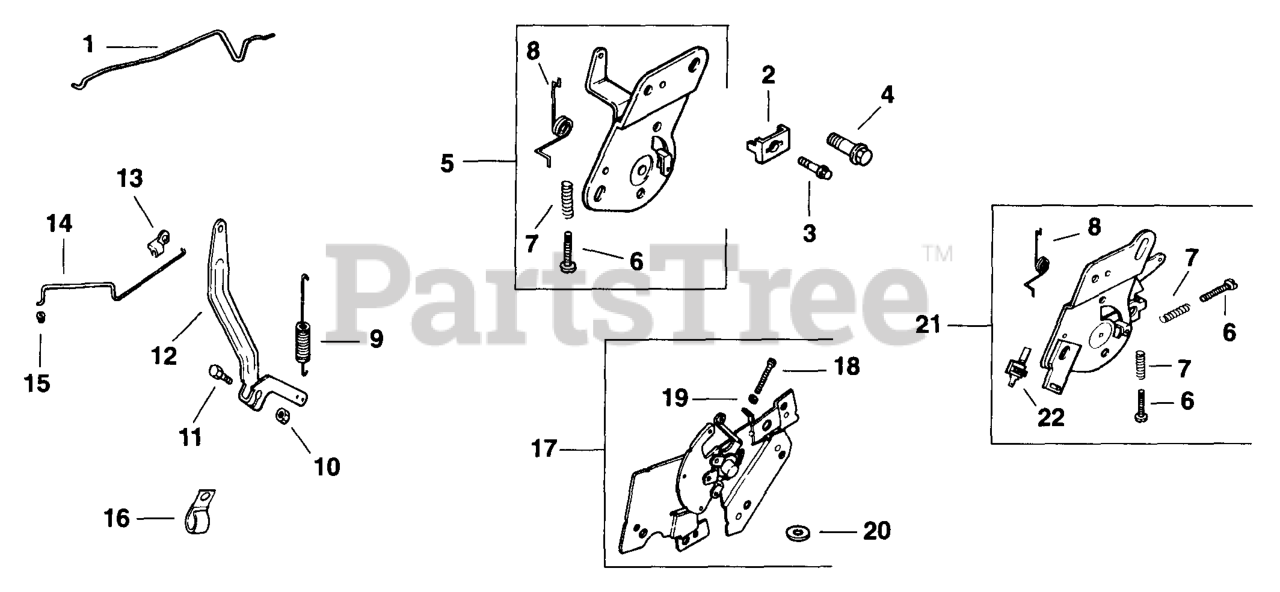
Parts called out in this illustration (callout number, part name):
1	LINKAGE, CHOKE
2	CLAMP, CABLE
3	Screw, hex. flange M5x0.8x16
4	SCREW - USE M-645016
6	Screw, pan hd. M4x0.7x25
7	SPRING, SPEED CONTROL (SHORT)
9	SPRING, GOVERNOR
10	Nut, hex. flange M6x1.0
11	USE SM-642025-S
12	LEVER KIT - USE 12 755 83
13	BUSHING, THROTTLE LINKAGE
14	LINKAGE, THROTTLE
15	BUSHING, LINKAGE RETAINING
21	CONTROL, SPEED
